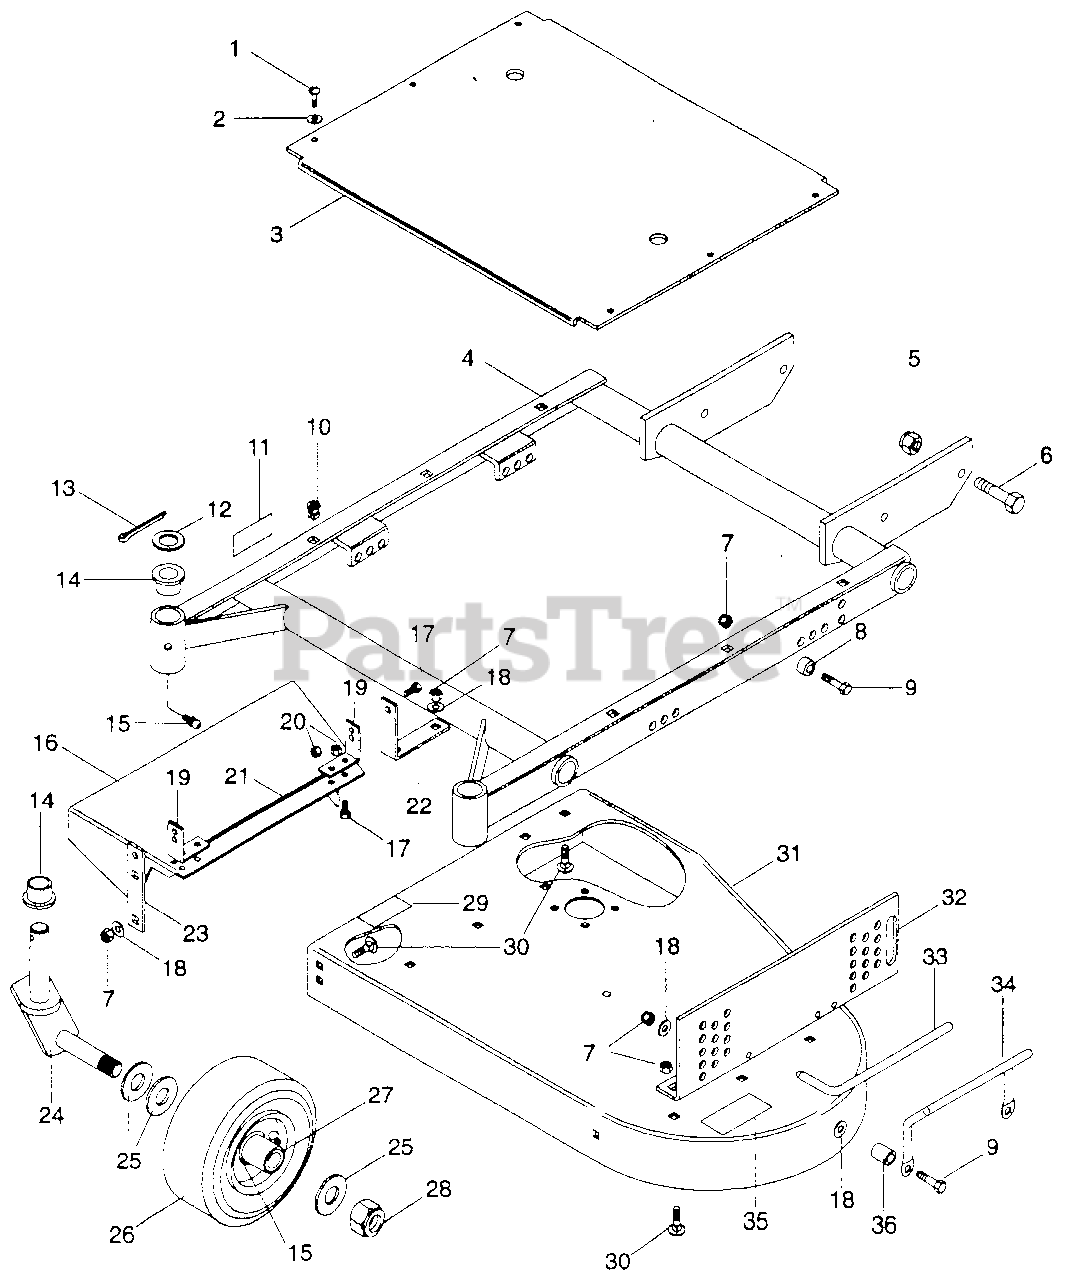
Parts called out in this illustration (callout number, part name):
1	SCR-TAP .25-20 X .50 HXSLHDPL
2	WSHR-FL-STL .281 X .625 X .065
3	CVR, SILKSCR
4	WLDT, MOWER FRAME, 36", PRO 150
5	NUT-LK-NYL .625-11 PL
6	BLT-HEX .625-11 X 1.50
7	NUT-LK-NYL .375-16 PL
8	BUSHING .391 X .626 X .670
9	BLT-HEX .38-16 X 1.50 PL GR 5
10	GRMT, PLASTIC
11	DECAL, DANGER HAND
12	BRG-R-THRST 1.002 X 1.552 X .030
13	PIN-COTR .188 X 1.50
14	BSHG-FLG 1.020 X 1.385 X .75 X 1.75 NY
15	FTG-LUBE .25-28 X .256
16	CHUTE, DISCHARGE
17	BLT-HEX .31-18 X .75 PL GR 5
18	WSHR-FL-STL .406 X .812 X .065 PL
19	BRKT
20	NUT-LK-NYL .312-18 PL
21	WIDTH OF CUT DECAL
22	BRKT
23	BRKT
24	WLDT, CASTOR FORK G44680
25	WSHR-FLAT .812 X 1.469 X .134
26	WHL 9 X 3.50
27	BRG, GA WHL
28	NUT-LK-NYL INSR .75-10 PL
29	DECAL, WARNING EYE
30	BLT-RDHDSQNK .38-16 X 1.0 PL
31	WLDMT, 36 DECK
32	BRKT, MWR SIDE SPRT L.H.
32	BRKT, MWR SIDE SPRT R.H.
33	PIN, MOWER LOCKING
34	HANDLE
35	DECAL, DANGER FOOT
36	BUSHING
NS	DECAL - GRAVELY LOGO
NS	DECAL - PRO 36
